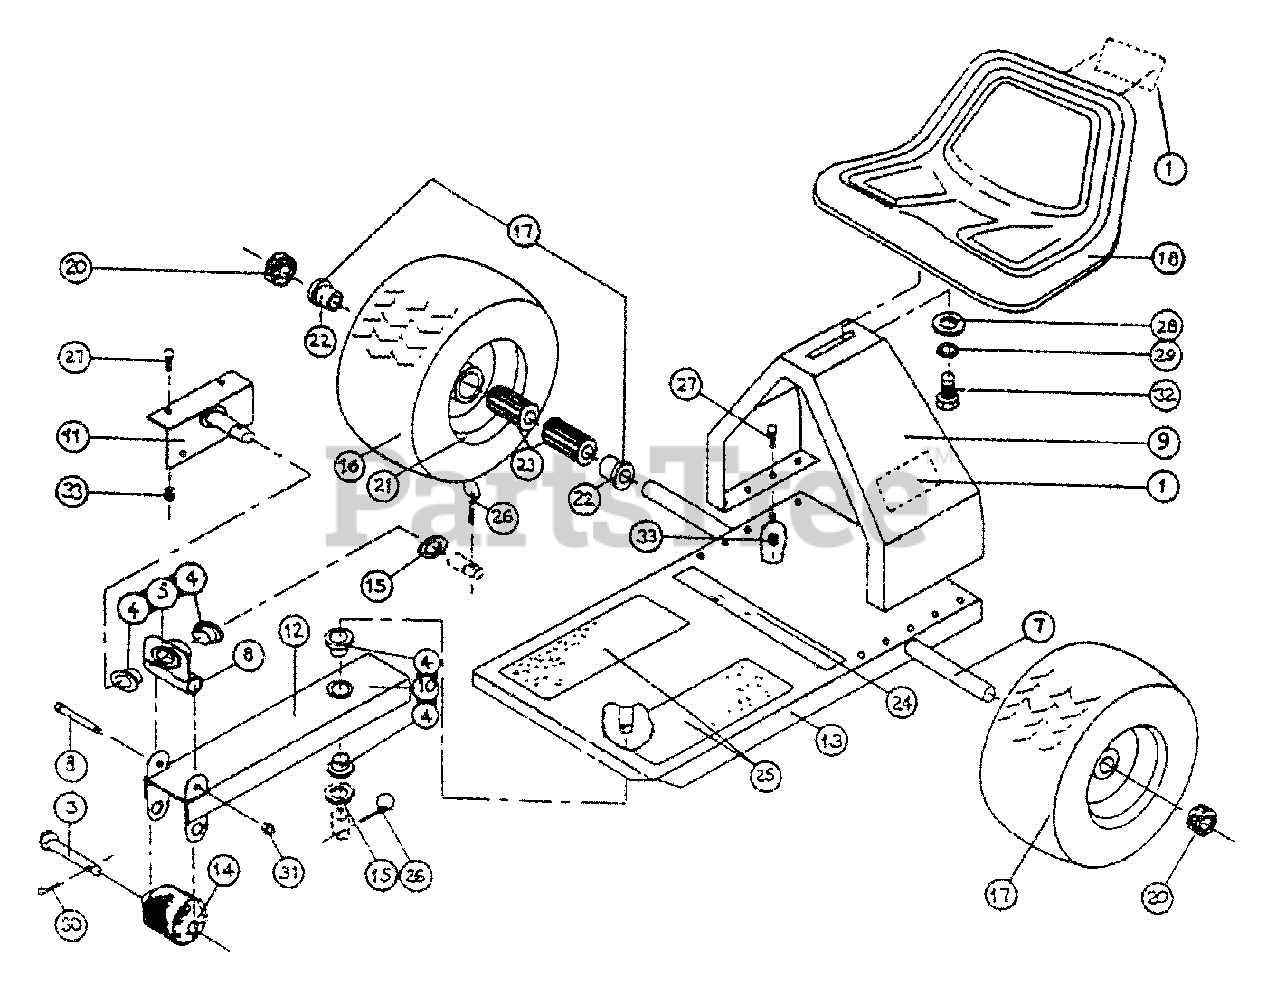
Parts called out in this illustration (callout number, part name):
1	Decal, Crown
3	Clevis Pin 1/2 x 4
4	Shoulder Bushing
5	Cross Weldment
6	Cross Assembly
7	Axle Weldment
8	Shoulder Bolt 1/2 x 3-1/4
9	Seat Mounting Weldment
10	Tongue Weldment
11	Hitch Weldment
12	Tongue Assembly
13	Deck w/Decal & Pads
15	7/8" Machinery Bushing
16	Tire, 13 x 6.5
17	Tire Assy., Complete
18	Sulky Seat
19	Zerk, 1/4-28 Straight
20	Clamp Collar, 7/8 I.D.
22	Flange Bearing
23	Roller Bearing
24	Warning Decal
25	Abrasive Pad
27	5/16-18 x 1 HHCS
28	1/2" Flat Washer
29	1/2" Split Lock Washer
30	Cotter Pin 1/8 x 1-1/2
31	3/8-16 HN, Center Lock
32	1/2-13 x 1 HHCS
33	5/16-18 HN, Nylon Insert
